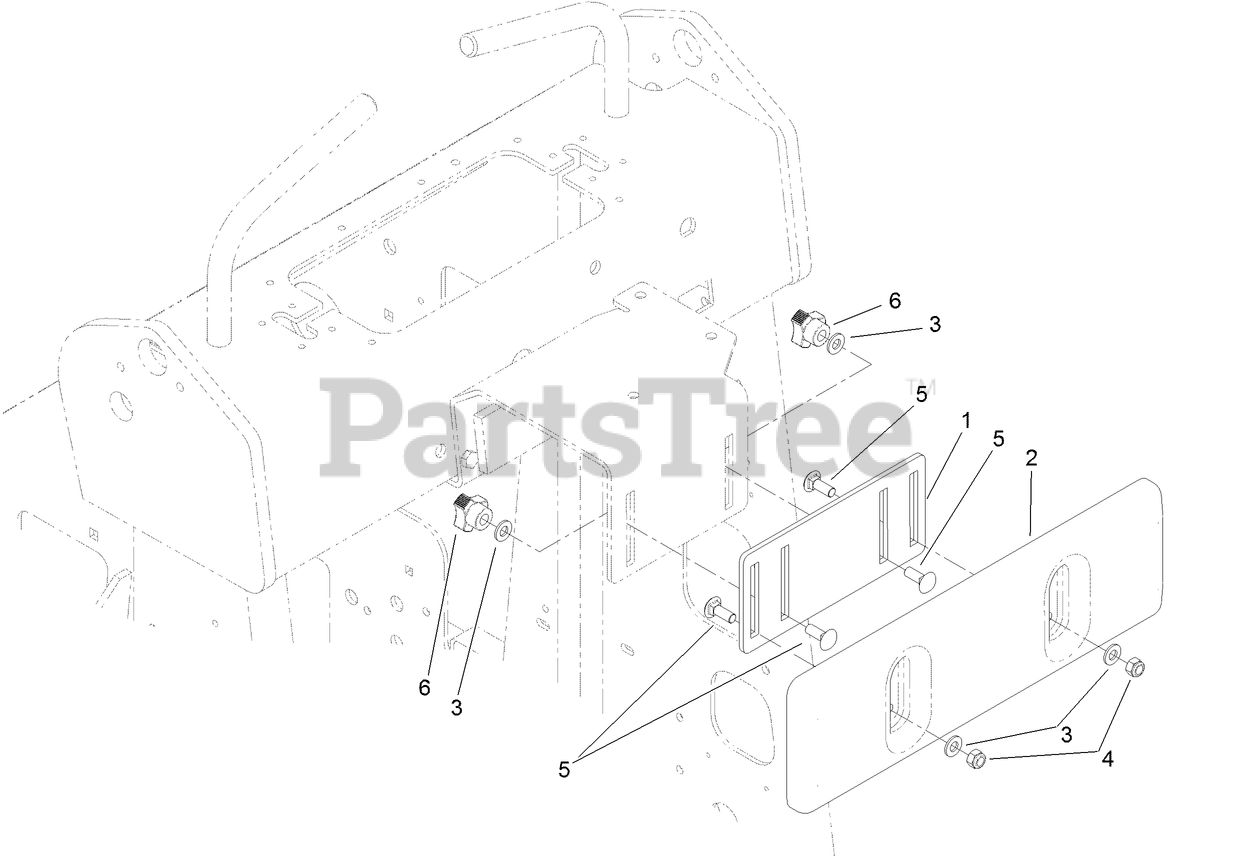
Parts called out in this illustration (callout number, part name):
1	PLATE-ADJUSTING
2	SUPPORT-THIGH
3	WASHER-FLAT
4	NUT-LOCK, NI
5	SCREW-CARR
6	Knob-Adjustment
